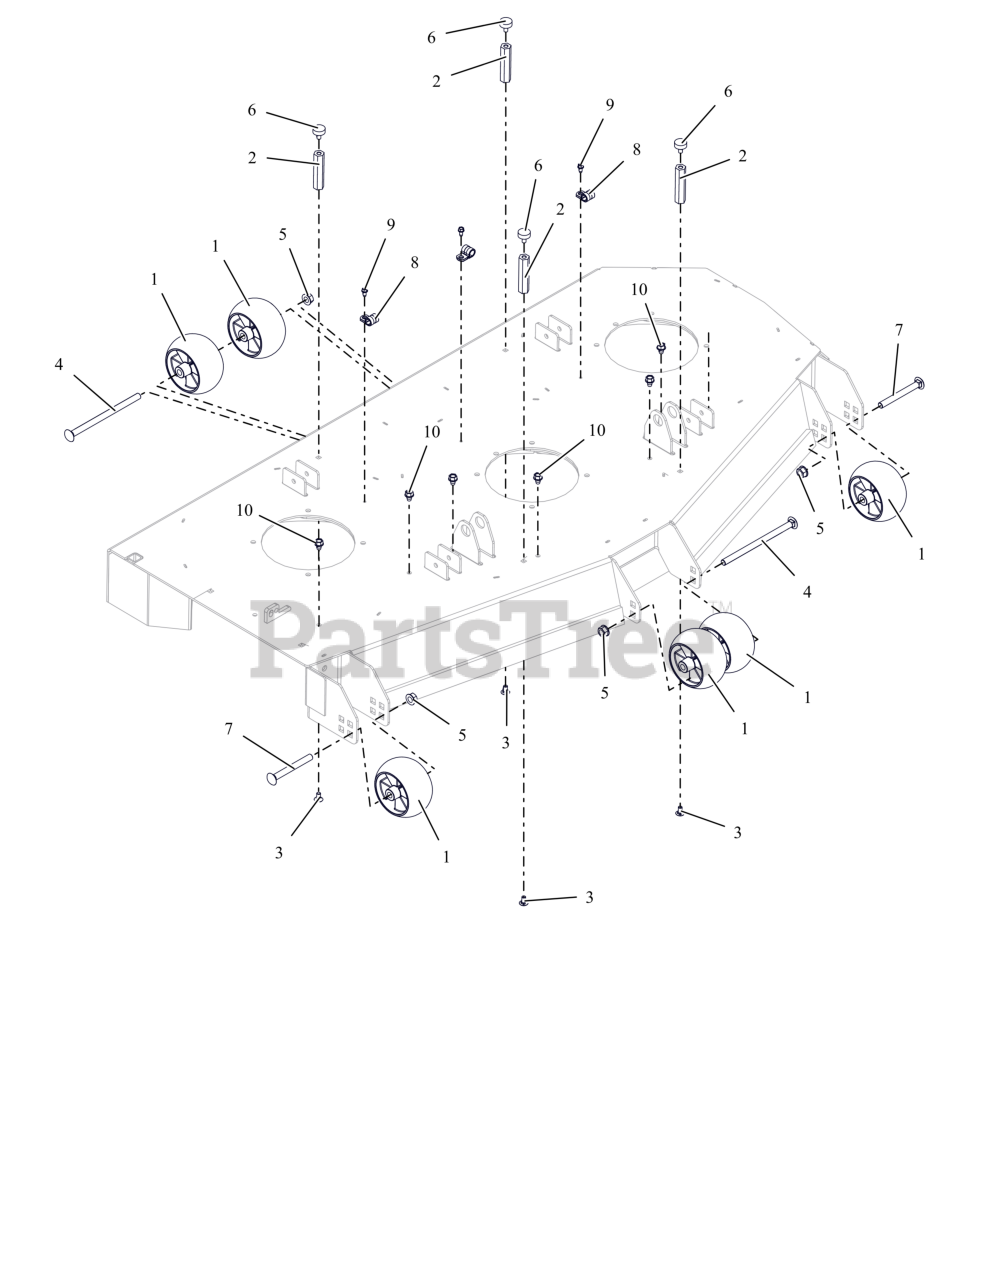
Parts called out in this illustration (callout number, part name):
1	WHEEL, ANTI SCALP - 5X3 CTR W/RIBS
2	NUT, COUPLING .312-18 X 3.375
3	BLT,RHSSN.31-18X.625 G5 ZCCP30
4	BLT-RHSN .50-13X8.00 G5 ZCC NS
5	NUT-LK-CTR-FLG .500-13 GG ZCC
6	BUMPER, RUBBER
7	BLT-RHNS .50-13X4.50 G5 ZCC NS
8	CLAMP, CUSHIONED STEEL
9	SCR-TAP .25-20X.50 HWH ZCC
10	SCR,TAP .375-16X.50 HWH TR ZCC
